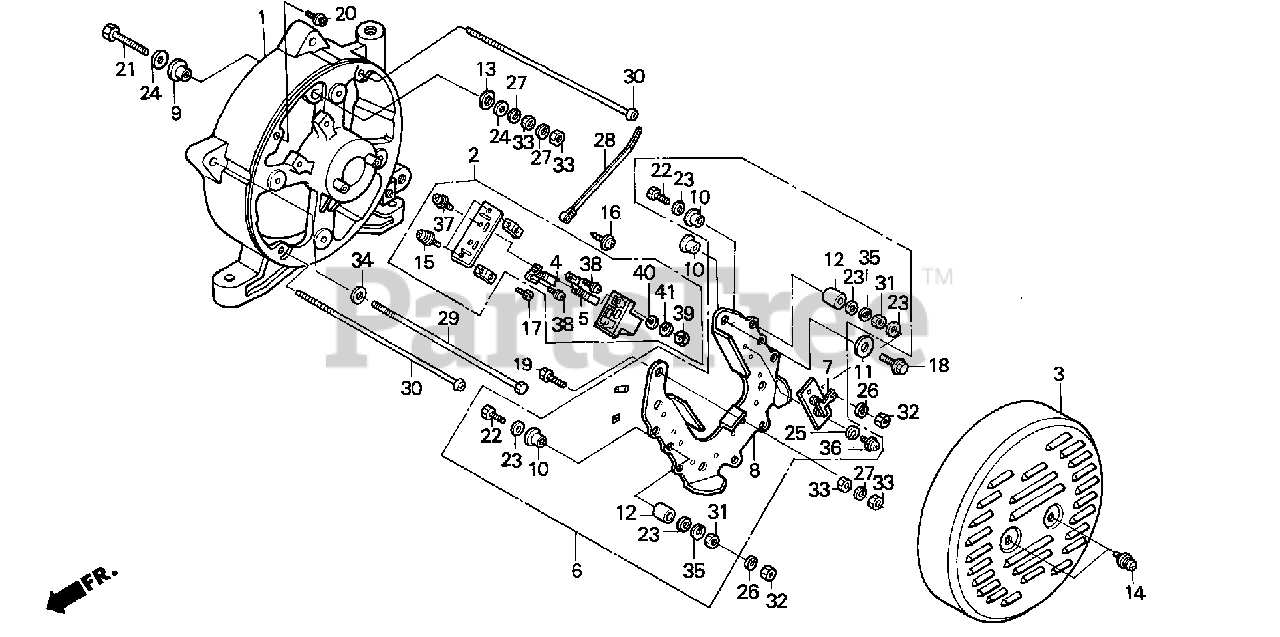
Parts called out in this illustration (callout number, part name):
1	HOUSING, RR.
2	HOLDER ASSY., BRUSH
3	COVER, GENERATOR END
6	DIODE ASSY.
8	PLATE, HEAT SINK
9	BUSH, INSULATING (6MM)
10	BUSH, INSULATING (5MM)
11	WASHER, INSULATING
12	INSULATOR (5MM)
13	WASHER, INSULATING
14	SCREW, TAPPING (5X8)
15	SCREW, TAPPING (5X14)
16	SCREW, TAPPING (4X10)
17	SCREW, TAPPING (5X14)
18	SCREW, TAPPING (5X16)
19	BOLT, HEX. (6X16)
20	SCREW, PAN (5X12)
21	BOLT, HEX. (6X30)
22	BOLT, HEX. (5X35) (NOT AVAILABLE)
22	BOLT, HEX. (5X35)
23	WASHER, PLAIN (5MM) (NOT AVAILABLE)
23	WASHER, PLAIN (5MM)
24	WASHER, PLAIN (6MM)
25	WASHER, SPRING (4MM)
26	WASHER, SPRING (5MM)
27	WASHER, SPRING (6MM)
28	TIE, CABLE
29	BOLT, HEX. (6X175)
30	BOLT, HEX. (5X215)
31	NUT, HEX. (5MM)
32	NUT, HEX. (5MM)
33	NUT, HEX. (6MM)
34	WASHER, PLAIN (6MM)
35	WASHER, SPRING (5MM)
36	SCREW, PAN (4X8)
37	SCREW-WASHER (4X16)
38	SCREW-WASHER (4X6)
39	NUT, HEX. (4MM)
40	WASHER, PLAIN (4MM)
41	WASHER, SPRING (4MM)
